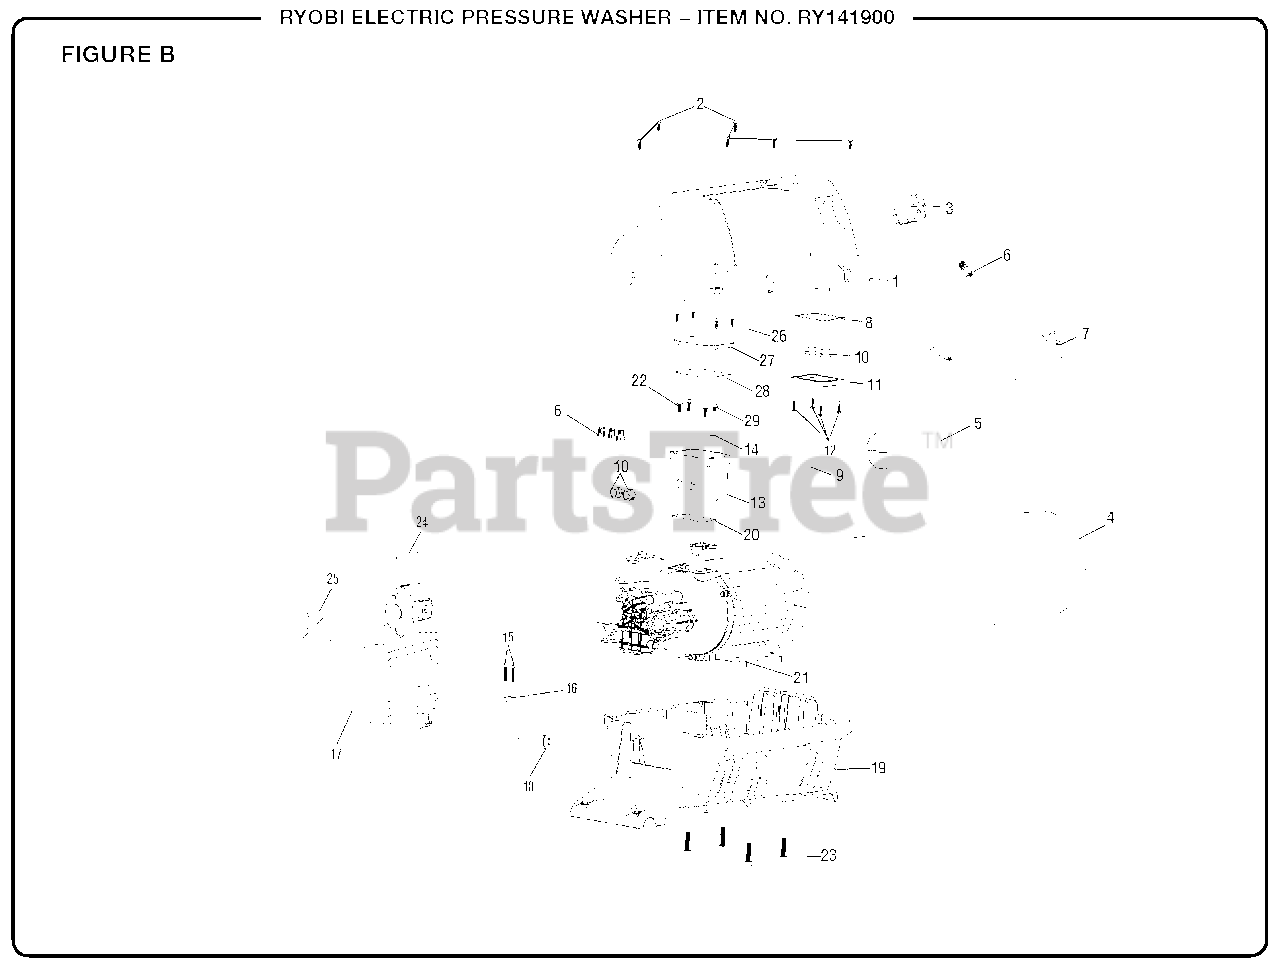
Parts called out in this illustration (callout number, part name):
1	Top Motor Housing
2	Screw (M4 x 15 mm)
4	Air Shroud
5	Capacitor
7	Connecting Wire
8	Switch Cover Gasket
9	O-ring (Capacitor)
11	Switch Cover
12	Screw (M3 x 14 mm)
14	Toothed Lock Washer
15	Screw (M3.5 x 20 mm)
16	Cord Clamp
17	Power Cord
19	Lower Motor Housing
20	Wire Box Gasket (Lower)
21	Motor and Pump Assembly
22	Bolt (M4 x 12 mm, Pan Hd.)
23	Bolt (M6 x 20 mm, Hex Hd. Locking)
24	Cord Plug Label
25	Cord Wrap Label
26	Screw (ST 3.5)
27	Wire Box Cover
28	Wire Box Gasket (Upper)
29	Bolt (M4 x 6 mm, Pan Hd.)
